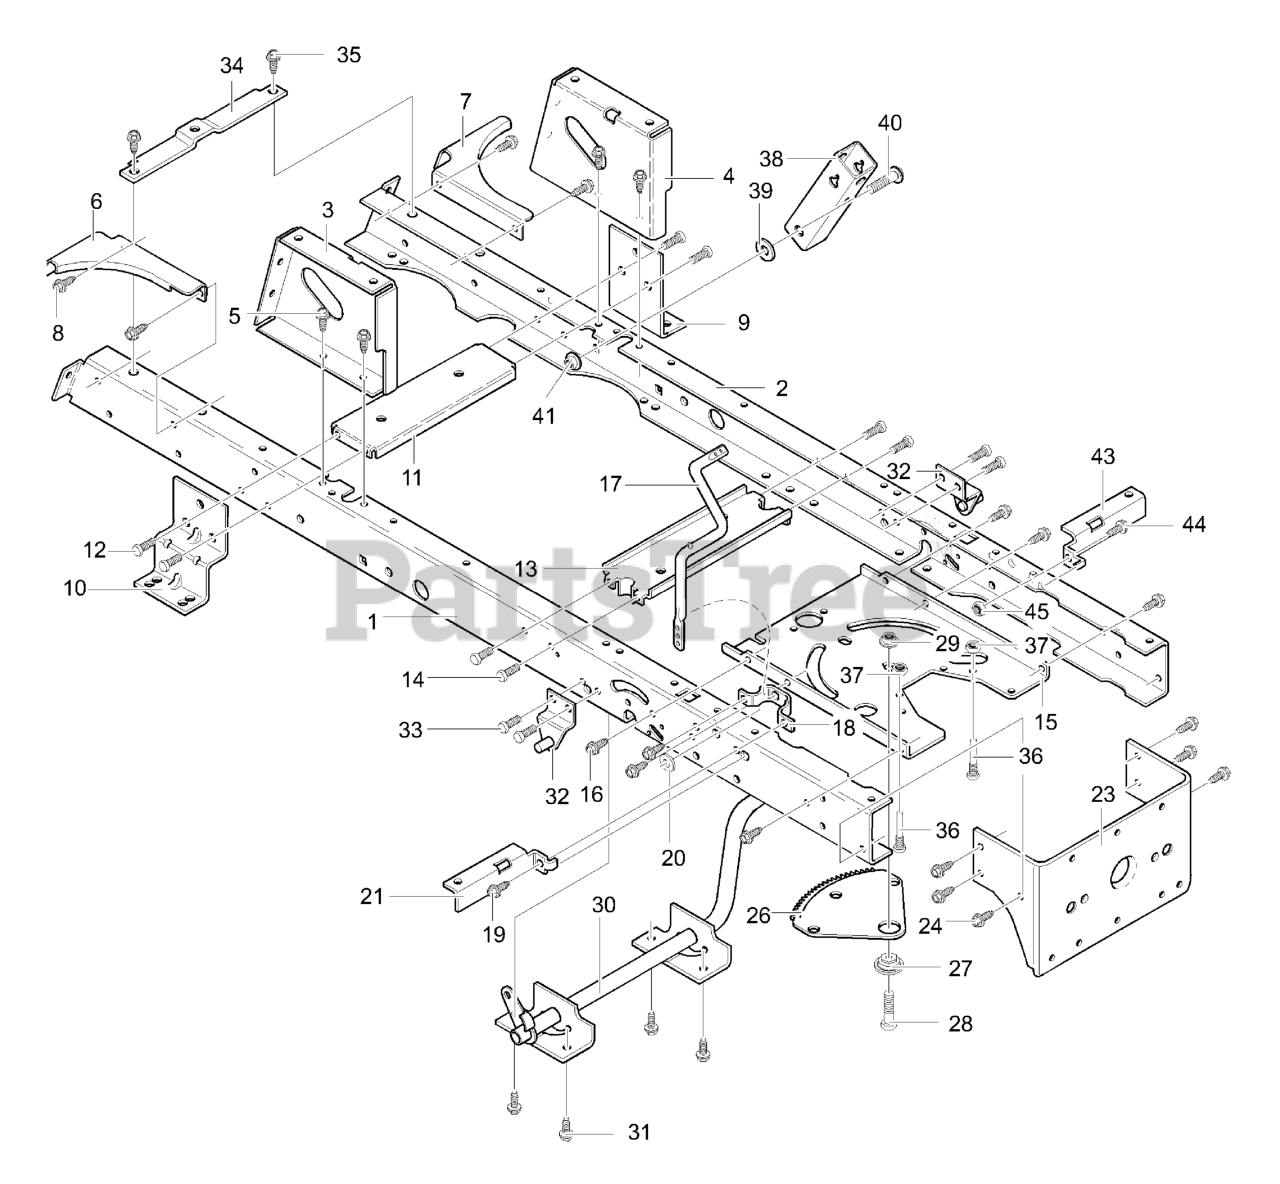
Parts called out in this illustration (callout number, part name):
1	Frame, Rail RH
2	Frame, Rail LH
3	Support, Seat RH
4	Support, Seat LH
5	Screw, .312-18x.75
6	Brace, Back Plate RH
7	Brace, Back Plate LH
8	Screw, .312-18x.75
9	Bracket, Transaxle
10	Bracket-TA RH-VST LH-MS
11	Asm., Idler Mount, Rear
12	Screw, .312-18x.75
13	Assy., Idler Mount, Front
14	Screw, .312-18x.75
15	Plate, Steering
16	Screw, .312-18x.75
17	Crank, PTO
18	Bracket, Bell Crank
19	Screw, .312-18x.75
20	Washer, Flat
21	Bracket, Seat Deck RH
23	Bracket, Hanger Rear
24	Screw, .312-18x.75
26	Gear, Sector
27	Bearing, Sector Gear
28	CAPSCREW, Hex Head, 5/16-18 x 1
29	Nut, 5/16-18
30	Clutch/Brake Pedal
31	Screw, .312-18x.75
32	Bracket, Suspension Asm.
33	Screw, .312-18x.75
34	Brace, Rail
35	Screw, .312-18x.75
36	Zinc Screw Guide
37	Nut, 5/16-18
38	Bracket, Pivot
39	Washer, Flat
40	Bolt, Shoulder 3/8-16
41	Nut, 3/8-16
43	Bracket, Seat Deck LH
44	Screw, .312-18x.75
45	Nut, 5/16-18
